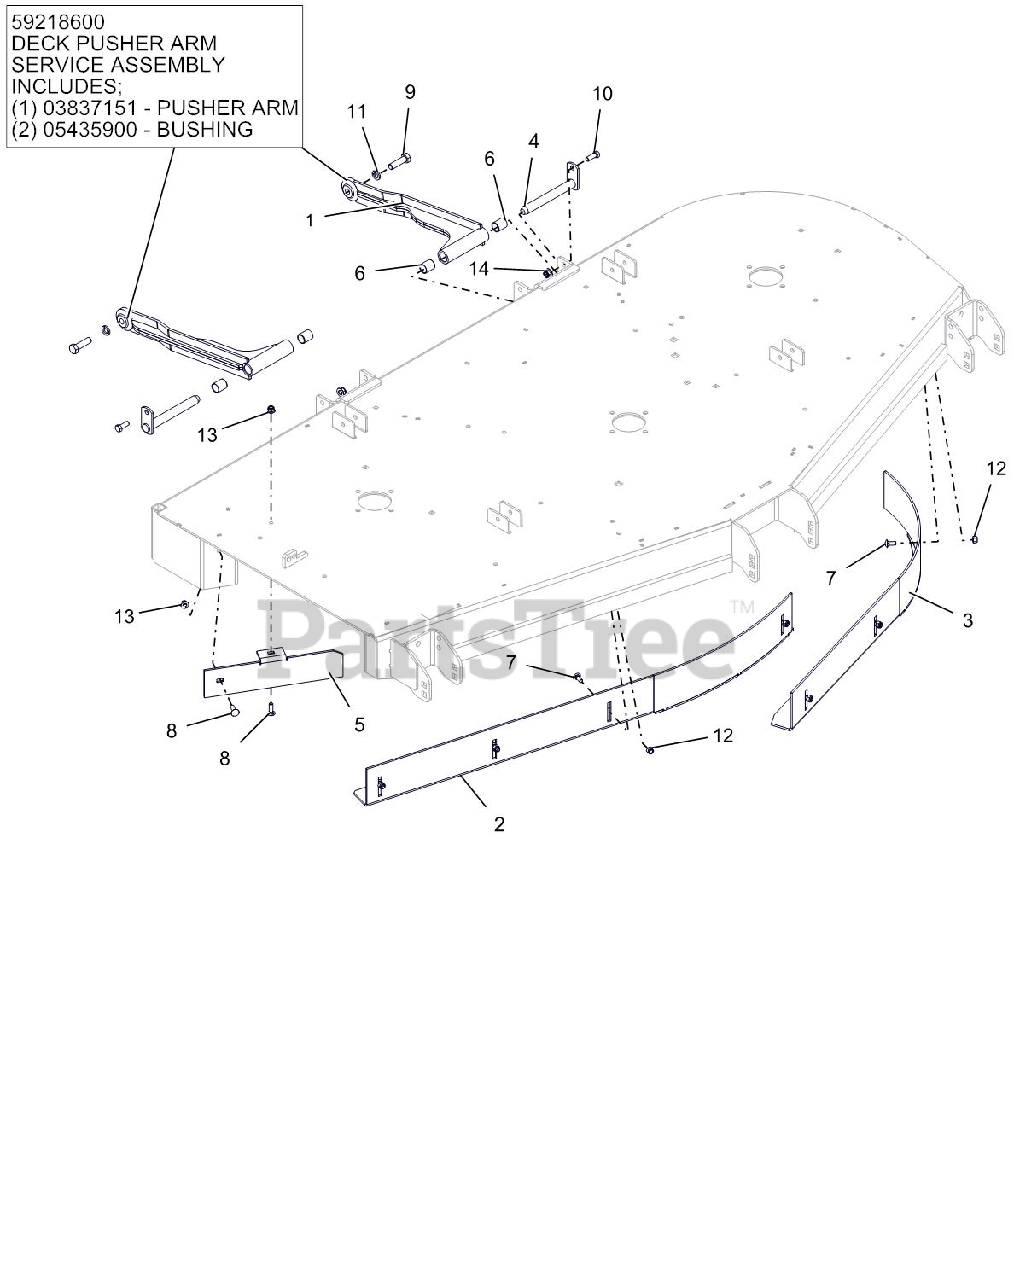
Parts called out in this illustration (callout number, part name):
1	BRG, .750 X .875 X 1.000
1	DECK STABILIZER ARM W/BUSHINGS
1	DECK STABILIZER ARM - BLACK
2	72" RH VACUUM BAFFLE WLDMT-BLK
3	72" LH VACCUM BAFFLE WLDMT-BLK
4	WELDMENT, MOWER MTG. PIN
5	72" DISCHARGE BAFFLE - RED
6	BRG, .750 X .875 X 1.000
7	@BLT-RDHDSQNK .31-18X.75 G5YZ
8	@BLT-RDHDSQNK .31-18X1.00 G5YZ
9	BLT-HEX .50-13X1.75 GR5EP80 YZ
10	@BLT-HEX .38-16X1.00 GR5 YWZC
11	@WSHR-LK .50X.125 REG YWZC
12	@NUT-LK-NYL .312-18 YWZC
13	@NUT-LK-NYL-FLG .31-18 YWZC
14	@NUT-LK-NYL-FLG .38-16 YWZC
